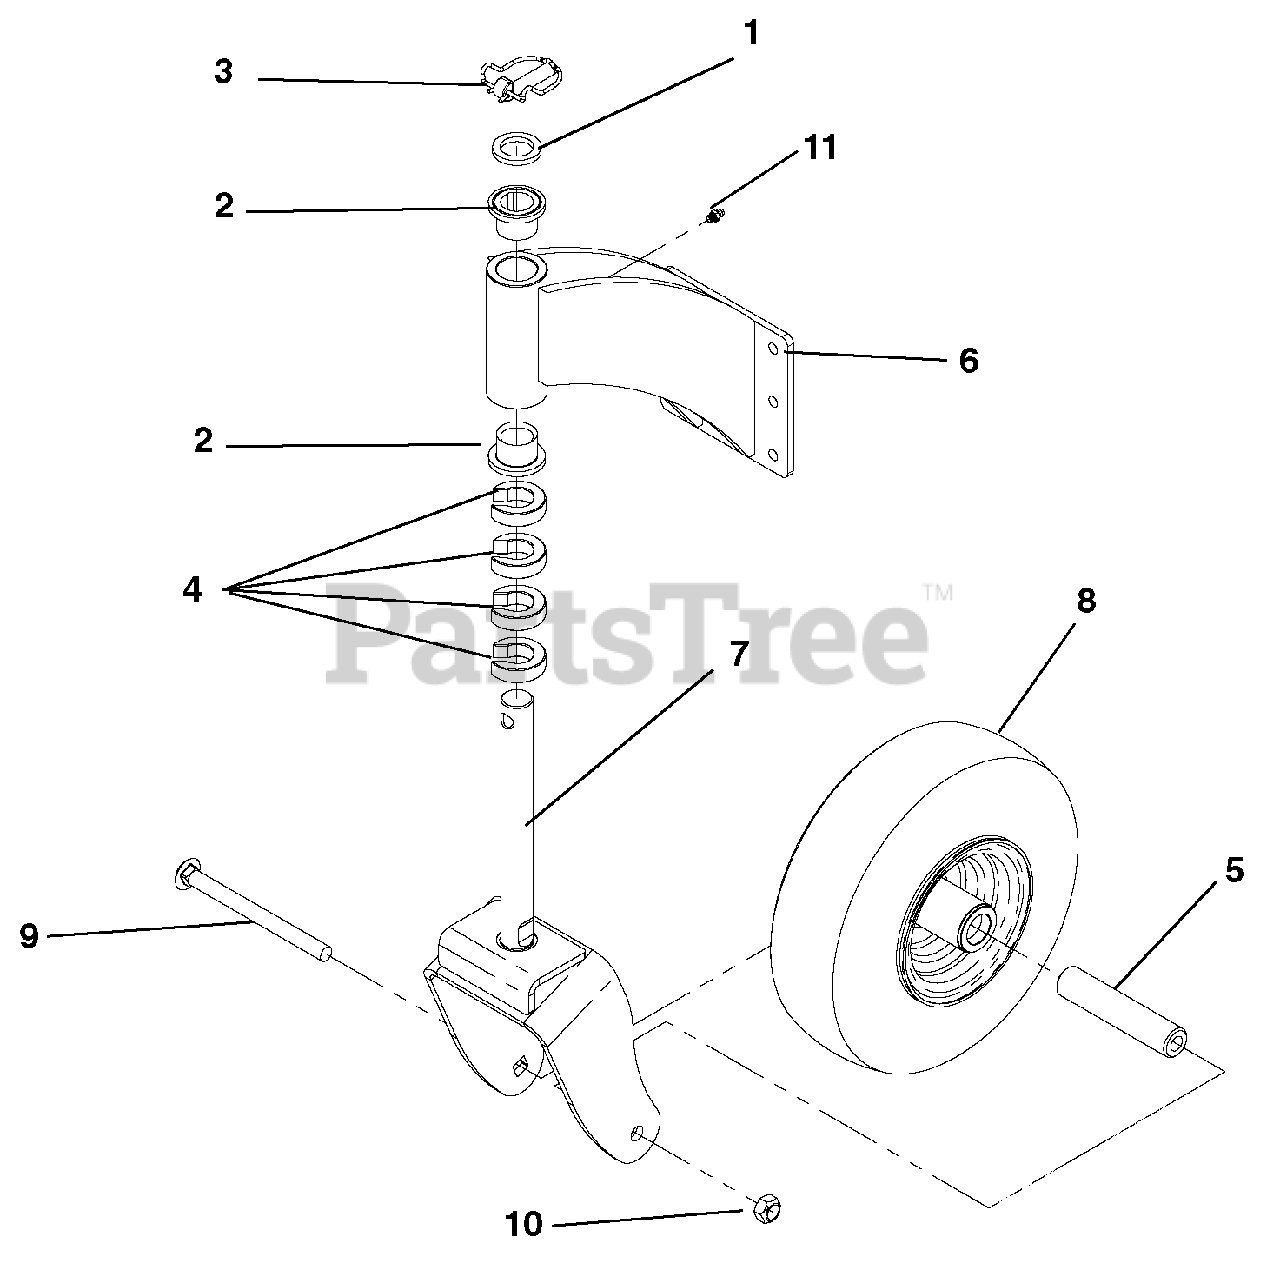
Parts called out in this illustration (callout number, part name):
1	Bushing, 1.03 x 1.50 x .179
2	Bearing, FLG 1.00 x 1.25 x 1.00
3	Pin, Lock .438 x 2.00
4	C-Spacer, 1.00 x 1.77 x .50 (48-inch Decks)
5	Tube, 1.00 x .50 x 4.76
6	Weldment, Caster Mount Bracket (48-inch Decks)
7	Weldment, Front Wheel Fork (48-inch Decks)
8	Wheel, Front 11 x 4 x 5
9	Bolt, 1/2-13 x 6.00 CRG
10	Locknut, 1/2-13 Crown
11	Grease Zerk, 1/4-28 STR .69 LG
